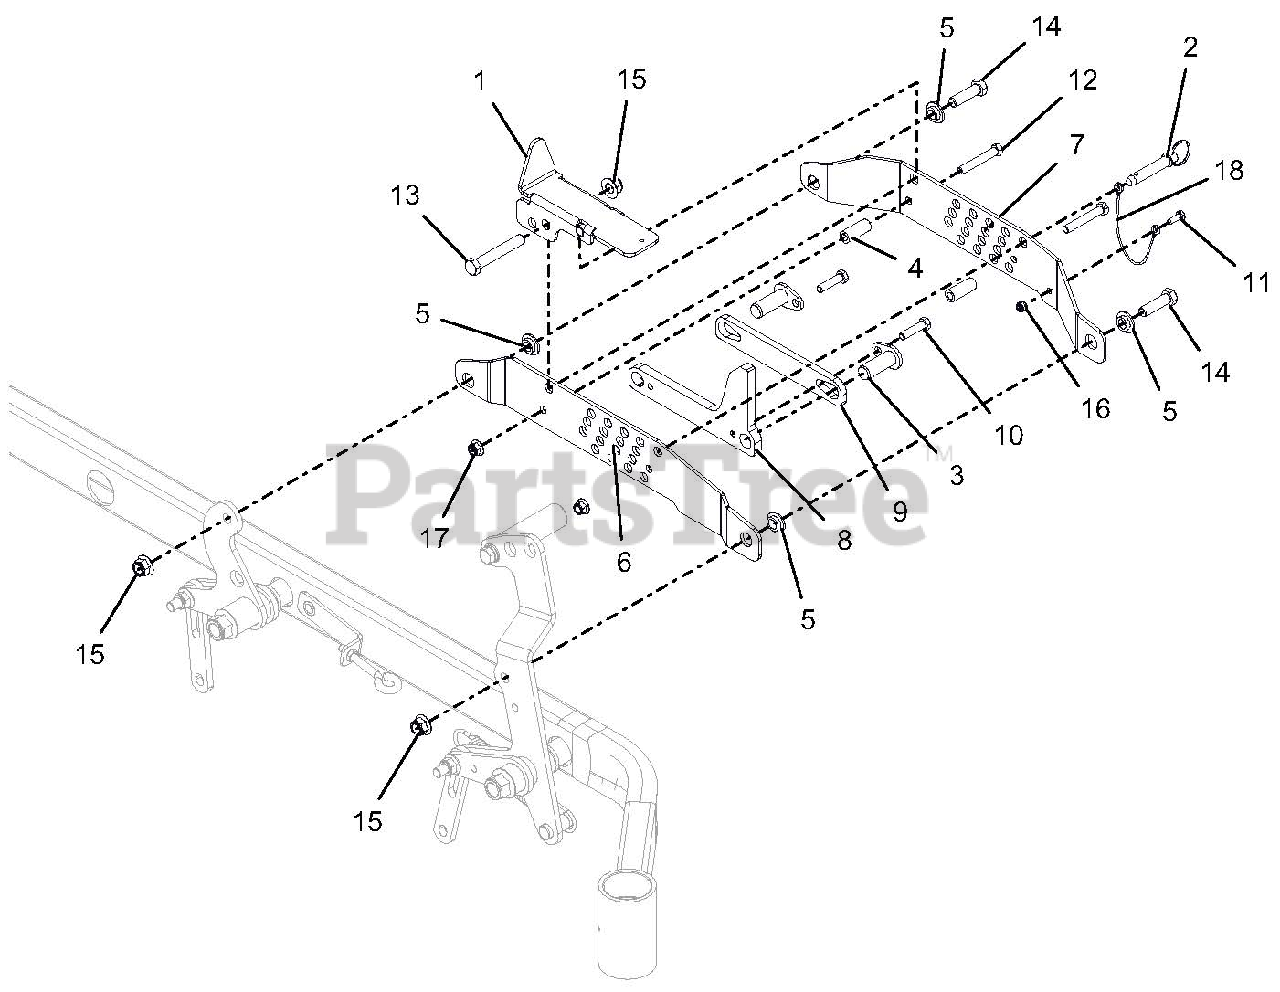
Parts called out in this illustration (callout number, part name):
1	WLDMT, MECHANICAL LOCK-UP-BLACK
2	PIN, .500 x 2.000 USABLE LG BALL
3	WLDMT, PIN
4	SPACER, .375 X .625 X 1.54
5	BSHG, FLANGE .515X.750X.31X1.12
6	BRKT, RH INBOARD LIFT/CUT HEIGHT-BLACK
7	BRKT, RH INBOARD LIFT/CUT HEIGHT-BLACK
8	BRKT, HOC STOP-BLACK
9	BRKT, HOC STOP-BLACK
10	BLT-HEX .38-16X1.50 GR5 YWZC EP30
11	BLT-HEX .25-20X.75 GR5 YWZC
12	BLT-HEX .38-16X2.50 GR5 YWZC
13	BLT-HEX .50-13X3.25 GR5 YWZC
14	BLT-HEX .50-13X1.75 GR5 YWZC
15	NUT-LK-NYL-FLG .50-13 YWZC
16	NUT-LK-NYL-FLG .25-20 YWZC
17	NUT-LK-NYL-FLG .38-16 YWZC
18	LANYARD, 12"
